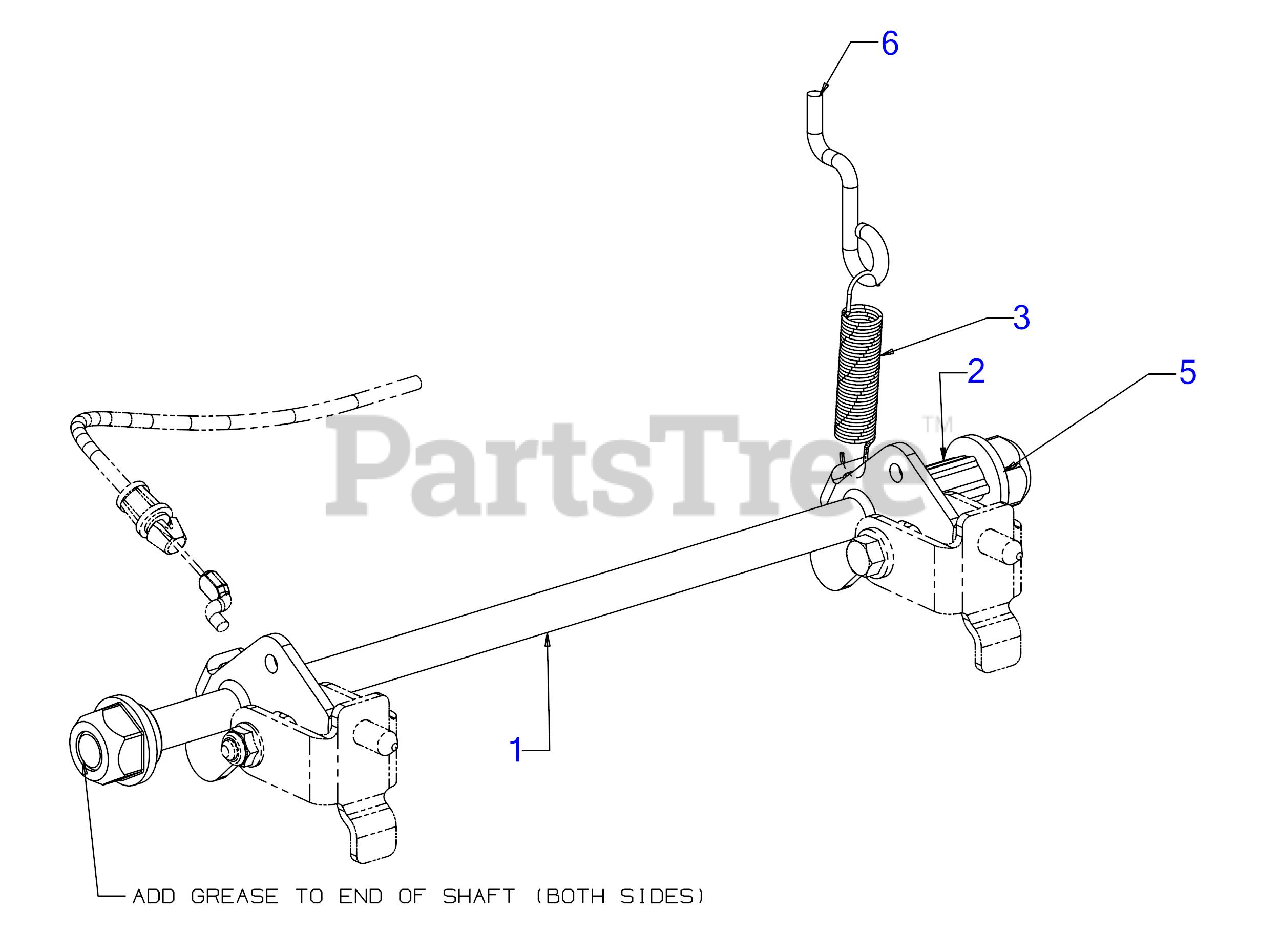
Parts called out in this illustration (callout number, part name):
1	LOCK LATCH ASSEMBLY
2	SNAP SPACER
3	EXTENSION SPRING .50 x 2.73
5	FLANGE BEARING
